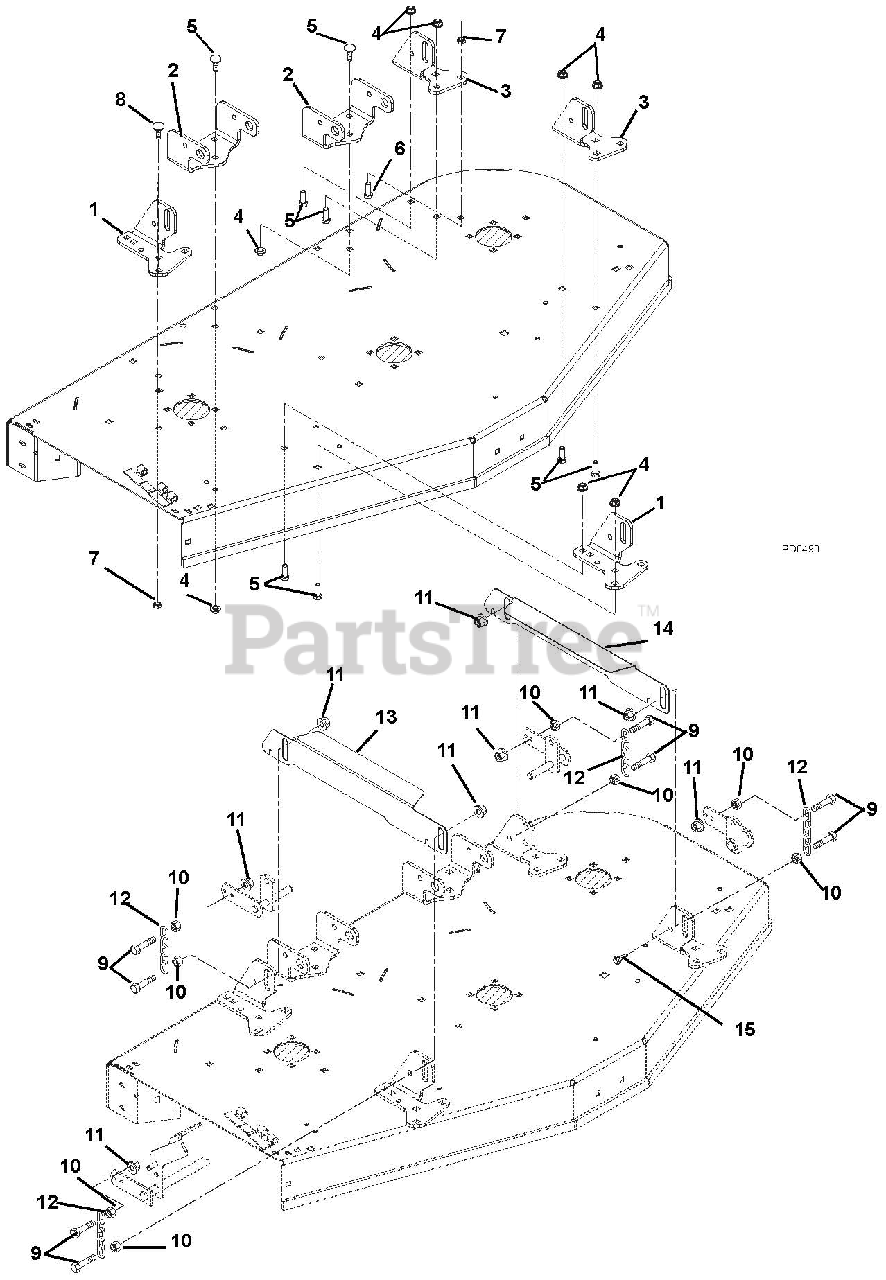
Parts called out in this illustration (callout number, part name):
1	Bracket, Deck Hanging
2	Bracket, Deck Mounting
3	Bracket, Deck Hanging
4	Nut, .38-16 Flange Nyloc
5	Bolt, Round Head Square Neck .38-16 x 1.00 Grade 5
6	Bolt, Round Head Square Neck .38-16 x 1.25 Grade 5
7	Nut, Locking Jam .375-16
8	Bolt, Round Head Square Neck .38-16 x .75 Grade 5
9	Bolt, Hex M12-1.75 x 55 Grade 5
10	Nut, Spinlock Flange M12-1.75
11	Nut, Locking Top Flange M12-1.75
12	Chain, Link
13	Bracket, Deck Stabilizing RH
14	Bracket, Deck Stabilizing LH
15	Screw, Tapping .25-20 x .50 Hex Washer Head
